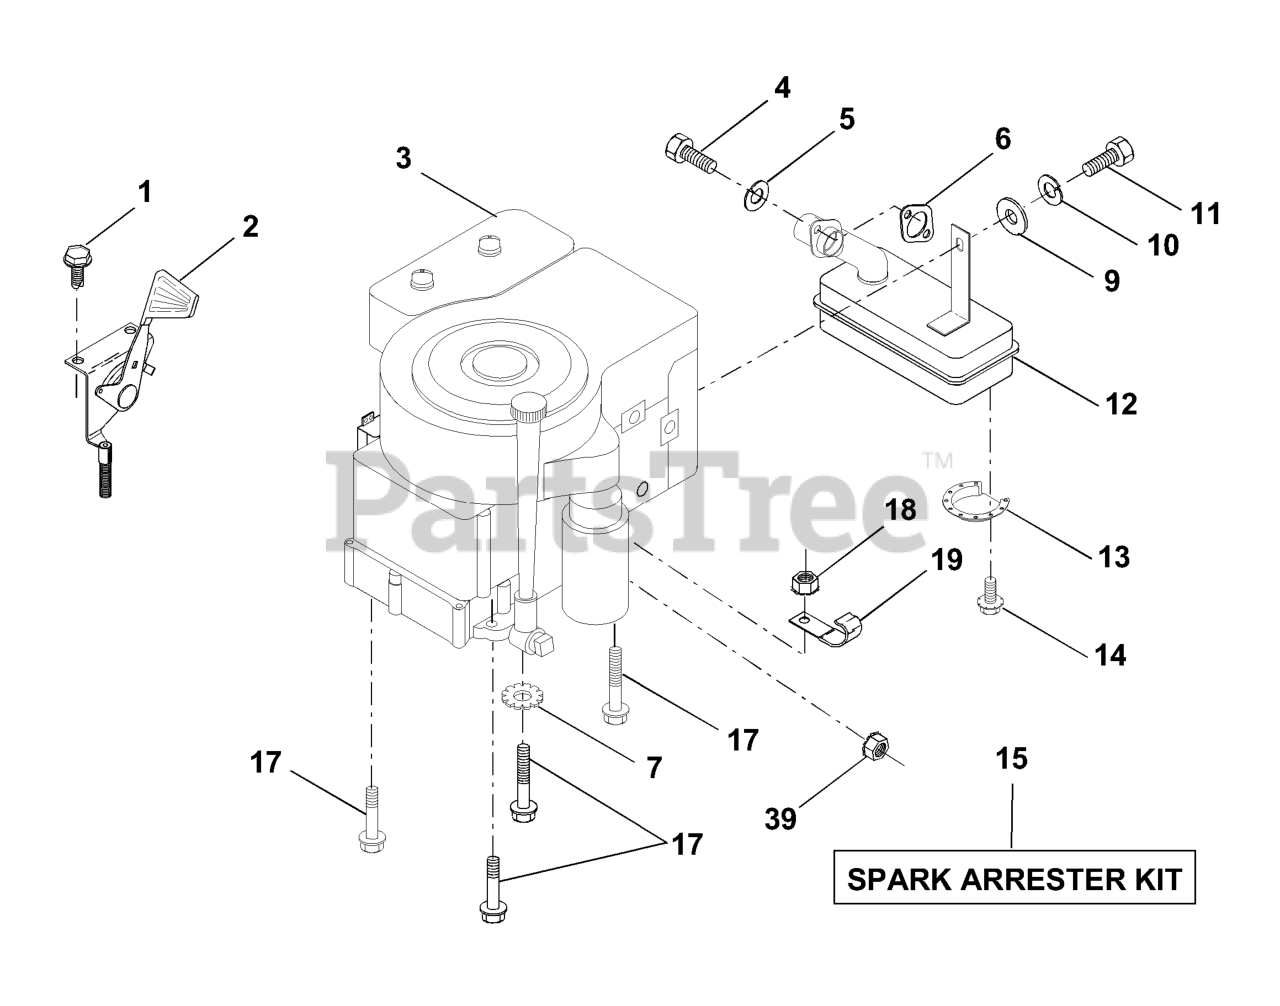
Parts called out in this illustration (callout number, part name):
2	CONTROL.TH/CH.RH.BLK.FLG.26
3	Engine, Briggs and Stratton Model No. 282707
4	SCREW
5	WASHER.LOCK.HVY.HLCL.SPR.5/16
6	GASKET ENGINE
7	LOCKWASHER
9	WASHER
10	LOCKWASHER
11	Bolt, Hex Fin.
12	MUFFLER.SINGLE.B&S.12HP
13	DEFL MUFFLER LTV
14	SCREW
15	KIT.SPARK ARRESTOR 794945 B&S
17	SCREW LT
19	CLIP T
39	NUT
